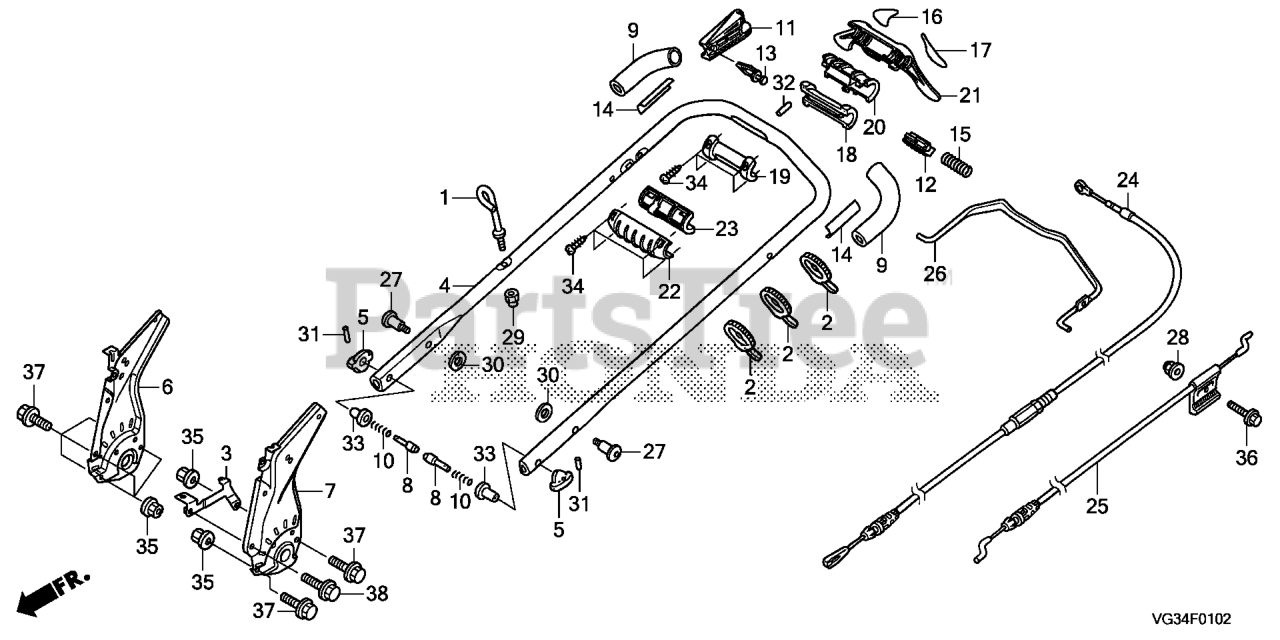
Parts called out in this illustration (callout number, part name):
1	GUIDE, ROPE
2	TIE, CABLE (157.5MM)
3	BRACKET, CABLE MOUNT
4	PIPE, HANDLE *NH105* (MAT BLACK)
5	GRIP, HANDLE JOINT *NH164* (GRIP GRAY)
6	STAY, R. HANDLE
7	STAY, L. HANDLE
8	PIN (8MM)
9	GRIP, HANDLE
10	SPRING, HANDLE ADJUSTING
11	STOPPER, LEVER
12	LEVER, SELECT
14	HOLD, GRIP
15	SPRING, SELECT LEVER
16	GRIP, R. PAD
17	GRIP, L. PAD
18	BRACKET, GRIP (UPPER)
19	BRACKET, GRIP (LOWER)
20	COVER, BRACKET (UPPER)
21	GRIP, CLUTCH (UPPER)
22	GRIP, CLUTCH (LOWER)
23	COVER, BRACKET (LOWER)
24	CABLE, CLUTCH
25	CABLE, BRAKE
26	LEVER, BRAKE *NH105* (MAT BLACK)
27	BOLT, SPECIAL (8X32)
28	NUT, NYLON LOCK (6MM)
29	NUT, NYLON LOCK (6MM)
30	WASHER (25MM)
31	PIN, COILED (2X12)
32	ROLLER (5X37.3)
33	COLLAR, HANDLE HEIGHT ADJUSTING
34	SCREW, TAPPING (4X12)
35	NUT, FLANGE (8MM)
36	BOLT, FLANGE (6X45)
37	BOLT, FLANGE (8X16)
38	BOLT, FLANGE (8X18)
